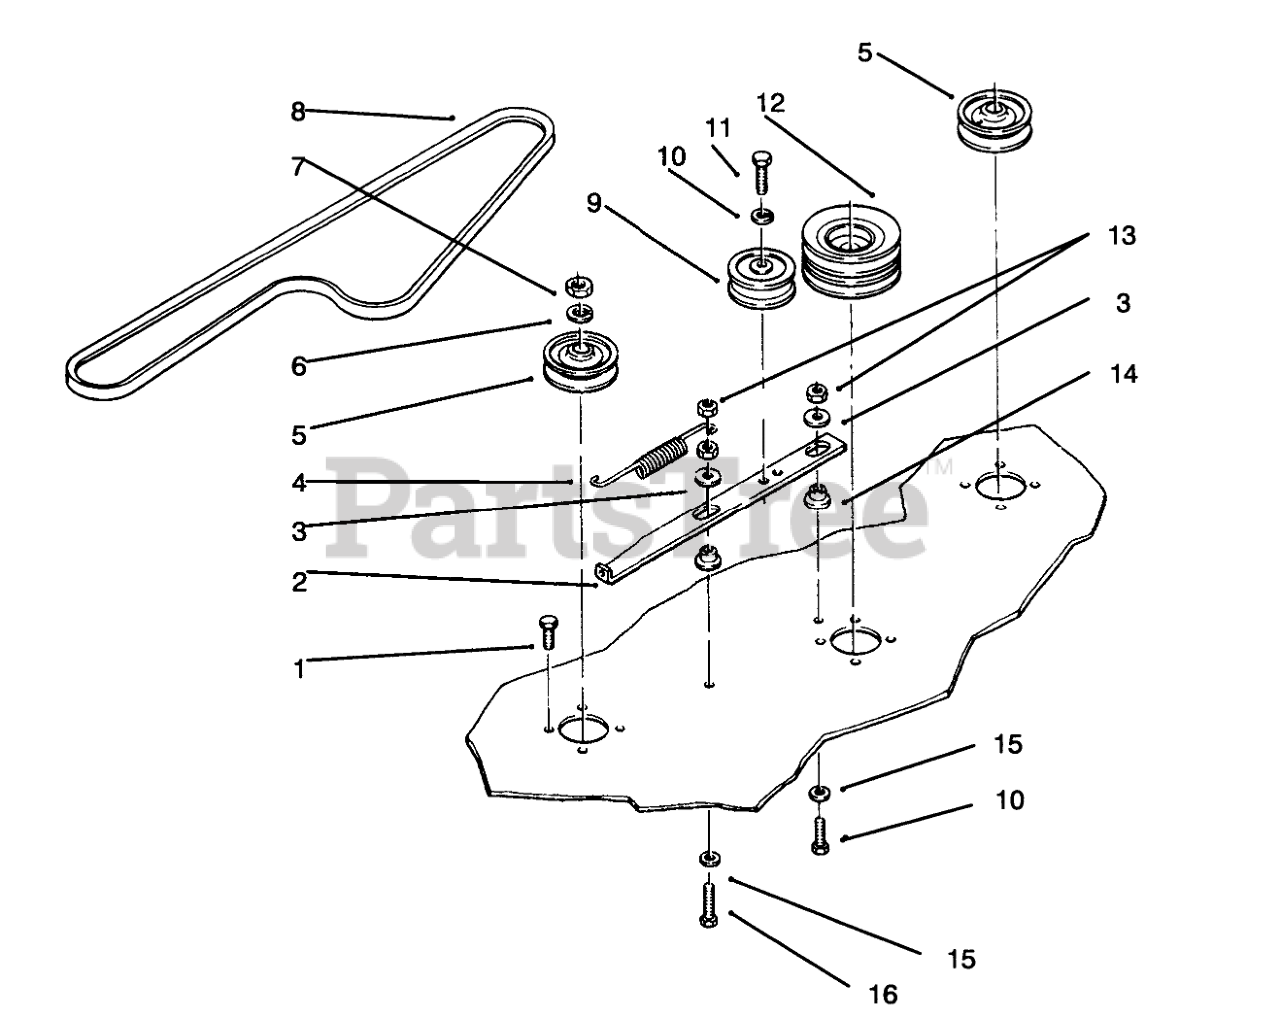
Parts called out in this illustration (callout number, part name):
1	SCREW-HH
2	BAR-IDLER SUPPORT
3	WASHER
4	SPRING-EXTENSION
5	PULLEY
6	WASHER-LOCK
7	NUT-JAM
8	V-BELT
9	PULLEY-IDLER
10	WASHER-LOCK
11	SCREW-HH
12	PULLEY CENTER
13	NUT-LOCK, NI
14	SPACER-BUSHING
15	WASHER
16	SCREW-HH
